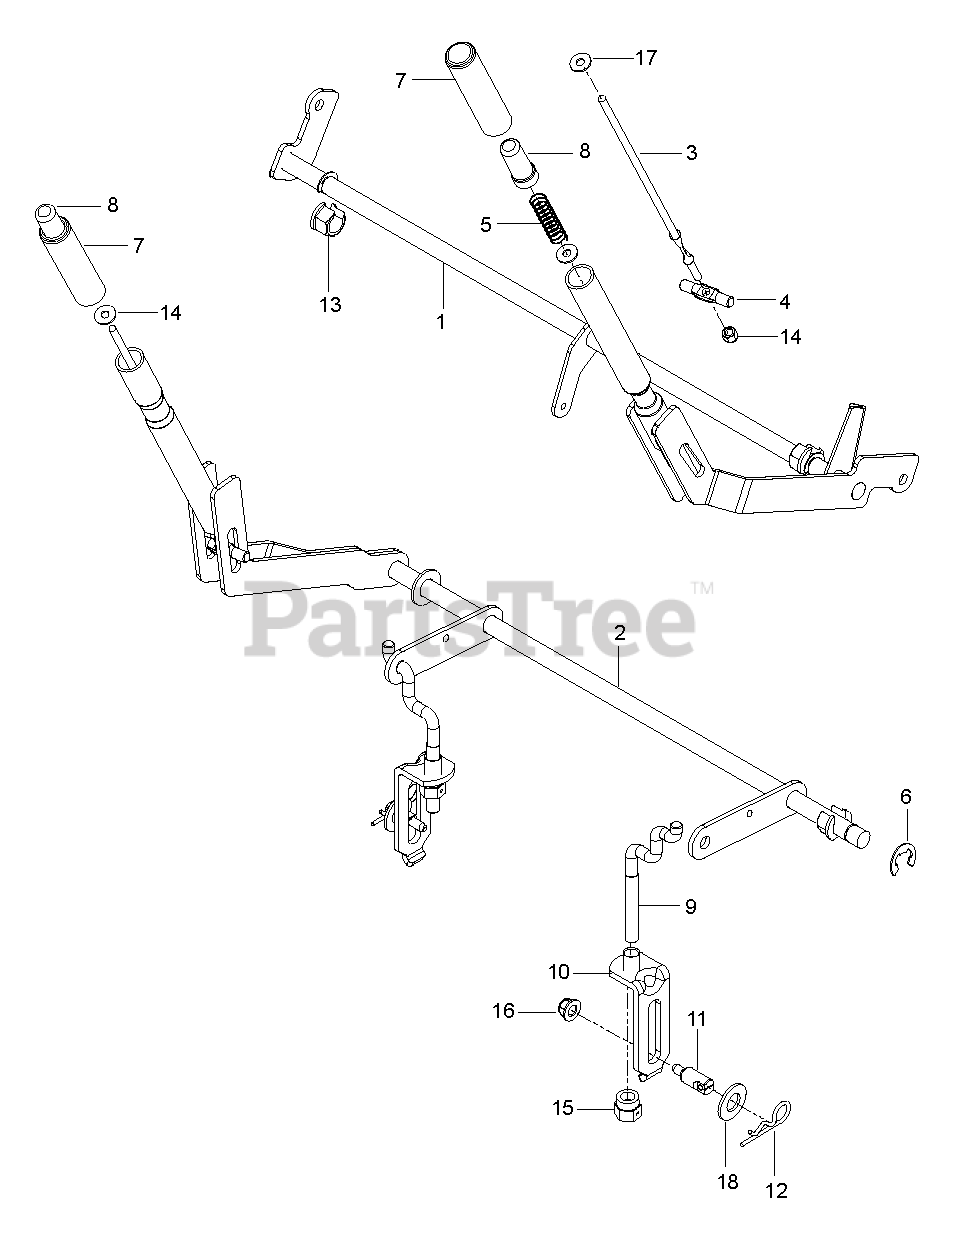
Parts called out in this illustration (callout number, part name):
1	SUB.ASM.SHAFT.BRAKE.WLDMNT.MED
2	DECK.LIFT.PNT.WELDMENT.RZ.BLK
3	ROD, HANDLE RELEASE
4	ROD LATCH RELEASE
5	SPRING, COMPRESSION
6	RETAINING RING LT
7	GRIP, HANDLE, BLACK 4"
8	BUTTON, PUSH, BLACK
9	LINK, REAR SUSPENSION
10	ASSEMBLY, BRKT LINK
11	STUD.FASTNER.W/ANTI-ROTATE
12	PIN.COTTER.7/16.BOW TI.
13	PLASTIC NUT
14	RP_NUT 1/4-20 NYLOC
15	NUT, LIFT LINK 7/16-20
16	NUT LOCK HEX FLANGE 5/16-18
17	WASHER PM
18	WASHER
